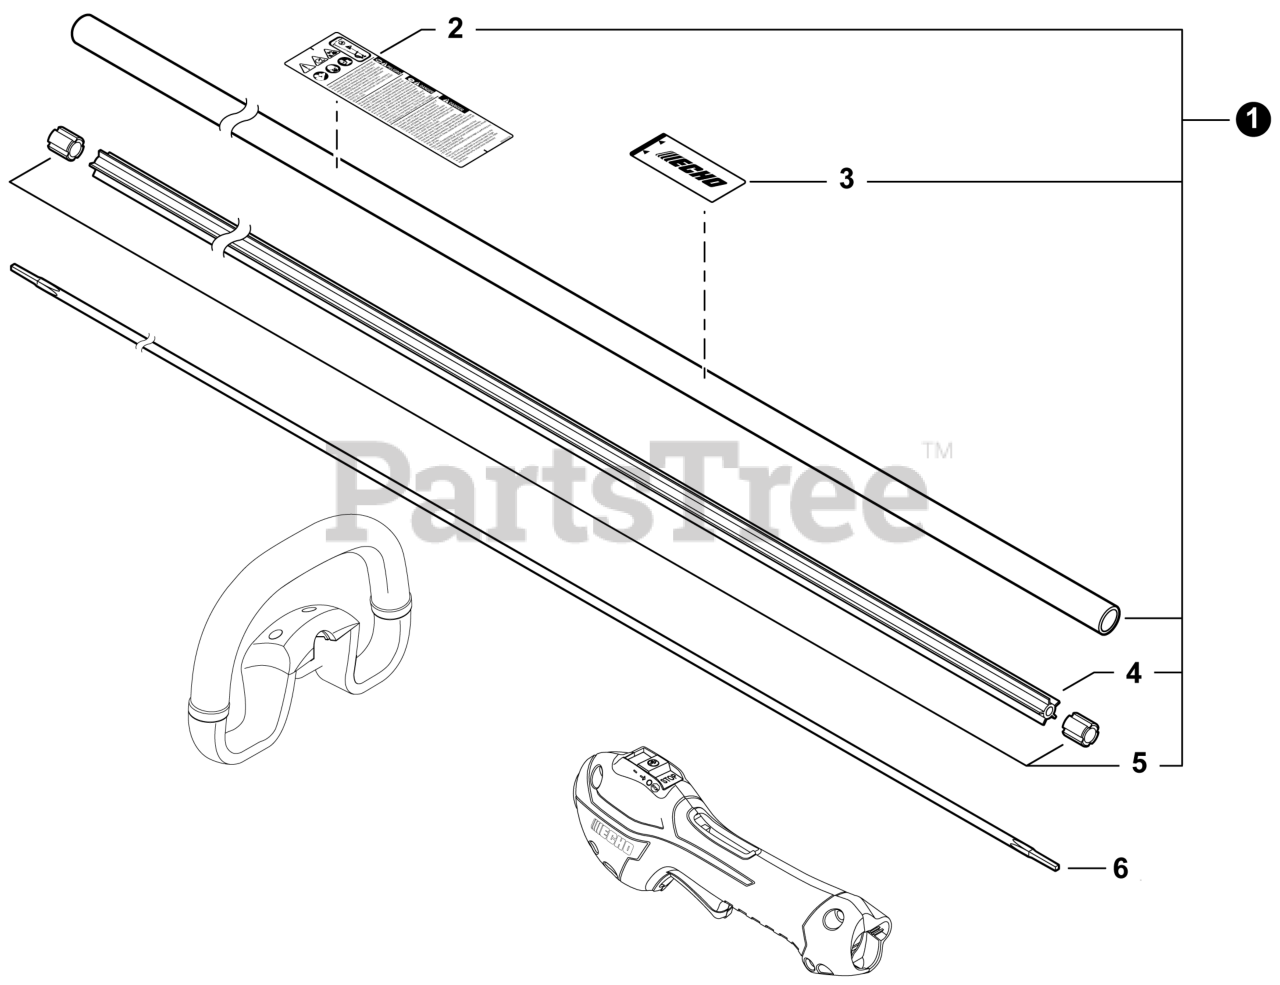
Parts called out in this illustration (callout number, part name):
1	MAIN PIPE ASSY
2	LABEL - CAUTION ISO
3	LABEL - HANDLE LOCATION
4	LINER, FLEXIBLE
5	STOPPER
6	DRIVESHAFT - FLEXIBLE
